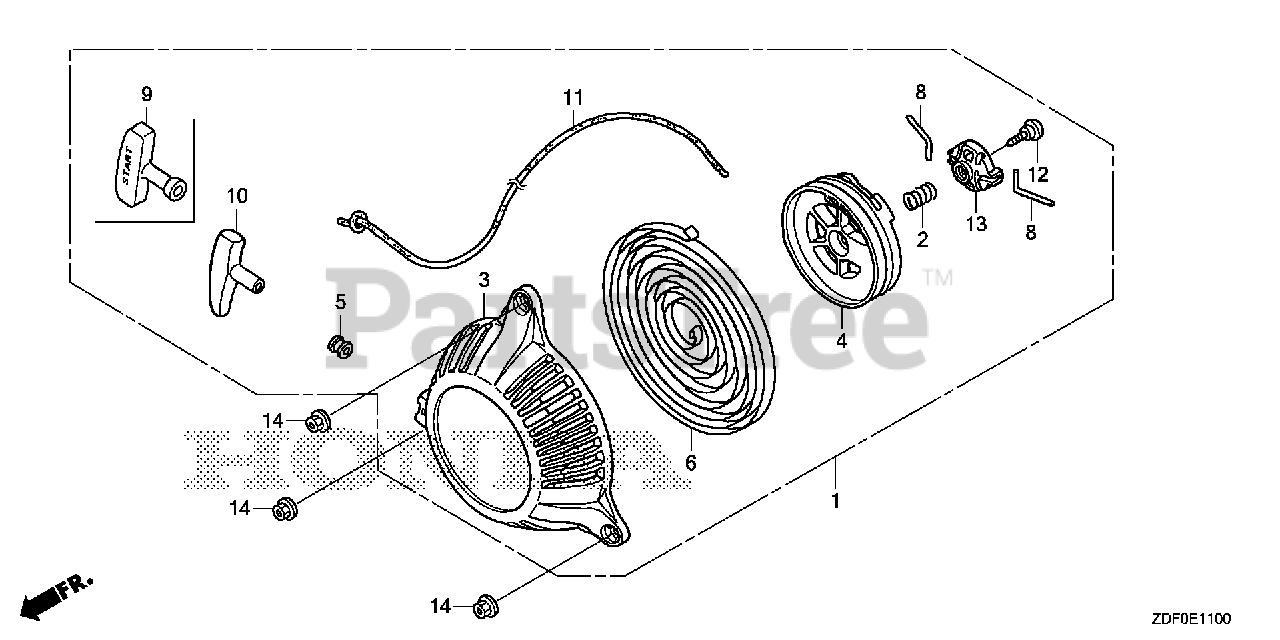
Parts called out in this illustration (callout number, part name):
1	STARTER ASSY., RECOIL
2	SPRING, FRICTION
3	CASE, STARTER
4	REEL, RECOIL STARTER
6	SPRING, RECOIL STARTER
9	GRIP, STARTER
11	ROPE, RECOIL STARTER
12	SCREW, SETTING
14	NUT, FLANGE (5MM)
